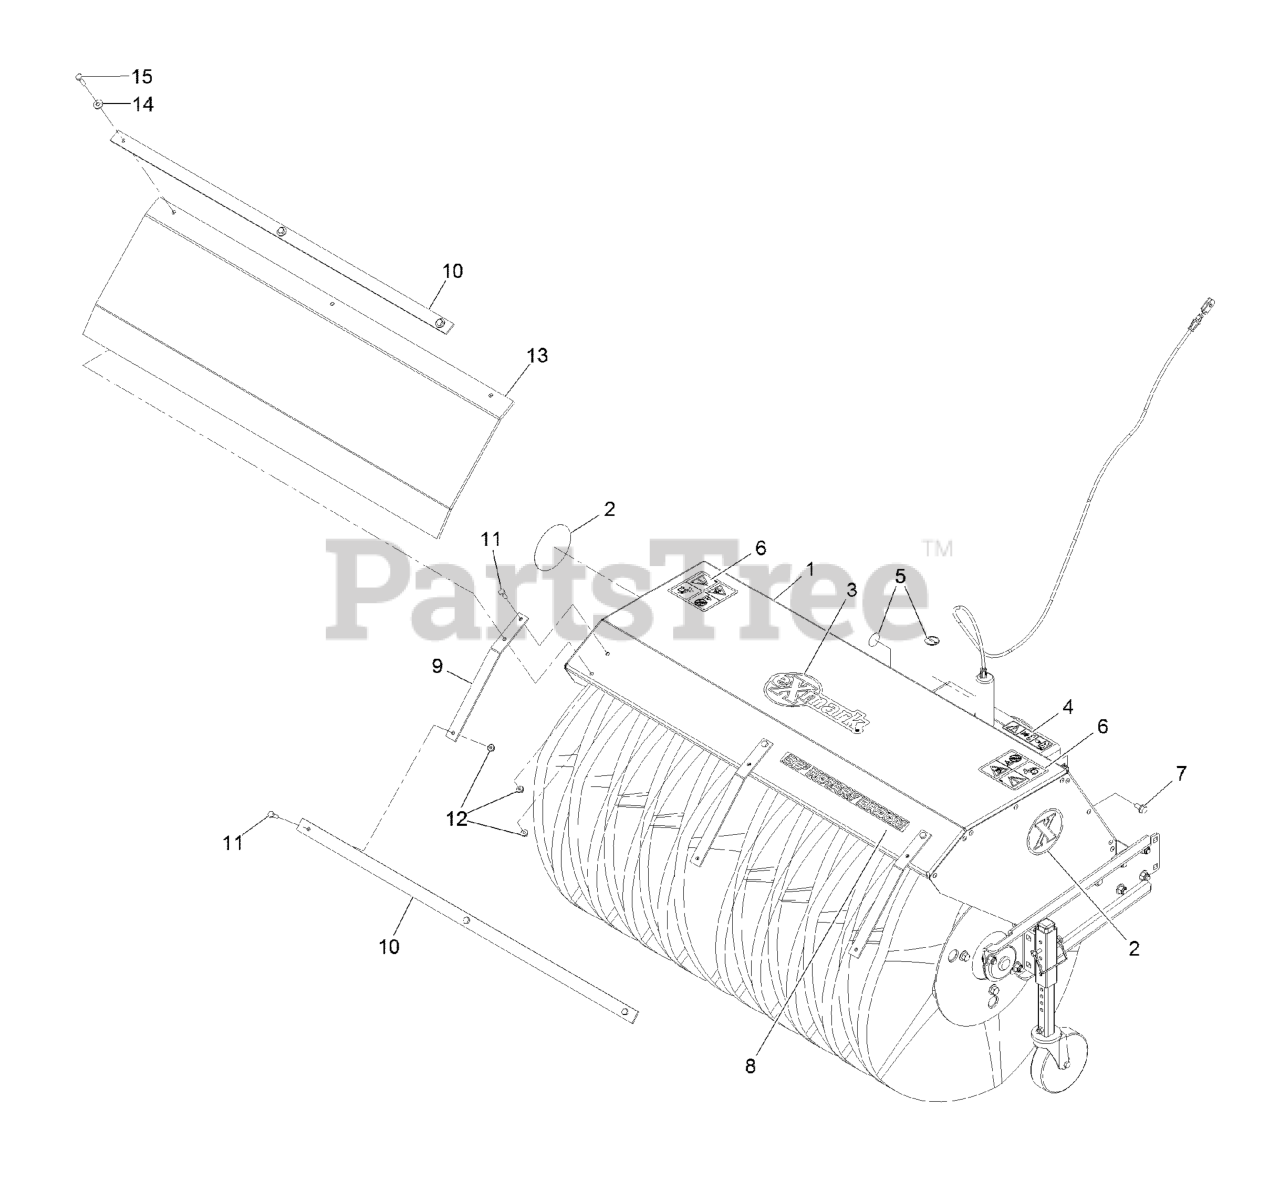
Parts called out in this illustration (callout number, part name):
1	Broom ASM
2	DECAL-EXMARK X-LOGO 3.85
3	DECAL, EXMARK LOGO
4	DECAL-COVER, MISSING
5	DECAL-GREASE
6	DECAL-WARNING
7	SCREW-HWHTF
8	DECAL-36 ROTARY BROOM
9	STRAP-SUPPORT, DEFLECTOR
10	STRAP-SUPPORT, BROOM DEFL
11	SCREW-HH
13	DEFLECTOR-BROOM
14	WASHER-FLAT
15	SCREW-HH
